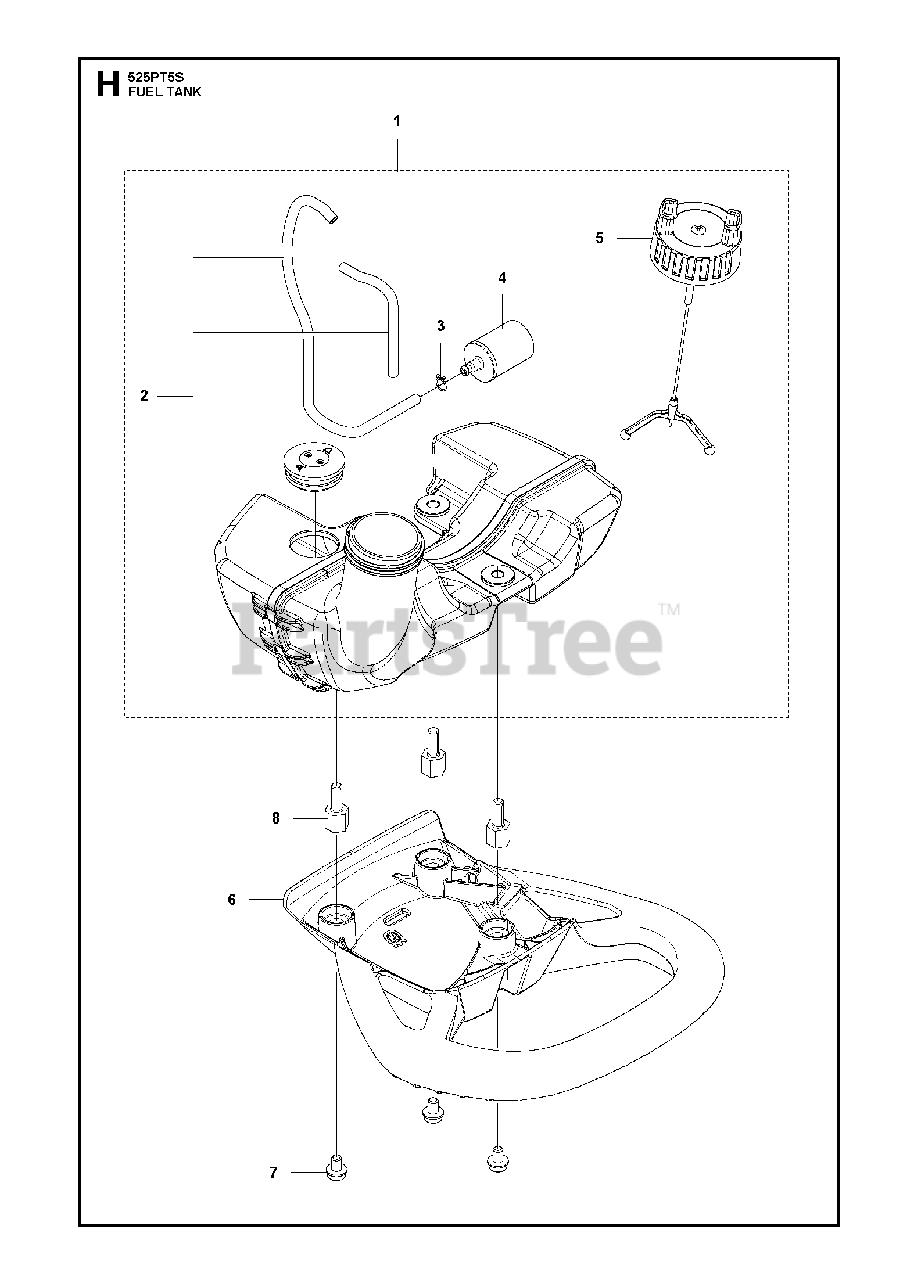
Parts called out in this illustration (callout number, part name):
1	FUEL TANK ASSY
1	FUEL TANK ASSY NBR+PVC
2	HOSE ASSY
2	PIPE
3	CLIP
4	FUEL FILTER
5	TANK CAP COMP
6	BUMPER ASSY
7	SCREW ITXSCM
8	STUD SCREW M5XM5
